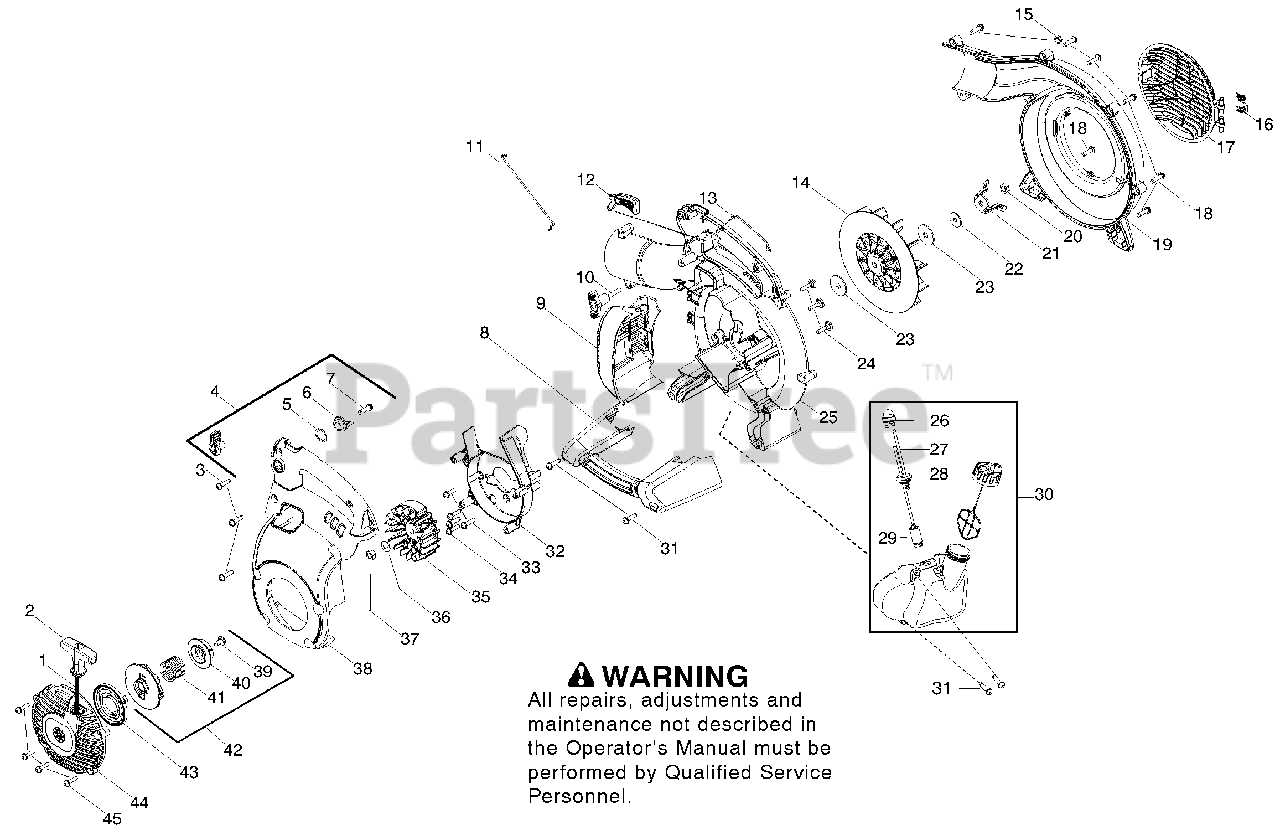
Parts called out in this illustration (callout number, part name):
1	Kit - Rope
2	Handle - Starter
4	Kit - Cruise control
5	Washer - Wave
6	Ratchet - Cruise control
8	Handle - Assist
9	Assy. - Muffler guard
10	Assy. - Knob tube clamp
11	Wire - Linkage
12	Trigger - Throttle
13	Wire - Handle ground
14	Impeller
15	Nut - Blower tube
16	Spring - Vac door
17	Cover - Vac door
19	Assy - Outer scroll
20	Nut - Impeller
21	Blade - Mulch
22	Washer
23	Washer - Impeller
25	Scroll - Inner
26	Bulb - Purge
27	Kit - Fuel line grommet
28	Assy - Fuel cap with retainer
29	Assy - Fuel pickup
30	Assy - Fuel tank
32	Scroll - Flywheel
34	Screw
35	Assy - Flywheel
37	Nut - Flywheel
38	Cover - Motor housing
41	Spring - EPS2
42	Kit - Starter
43	Spring - Starter
44	Housing - Starter Cover
45	Screw
